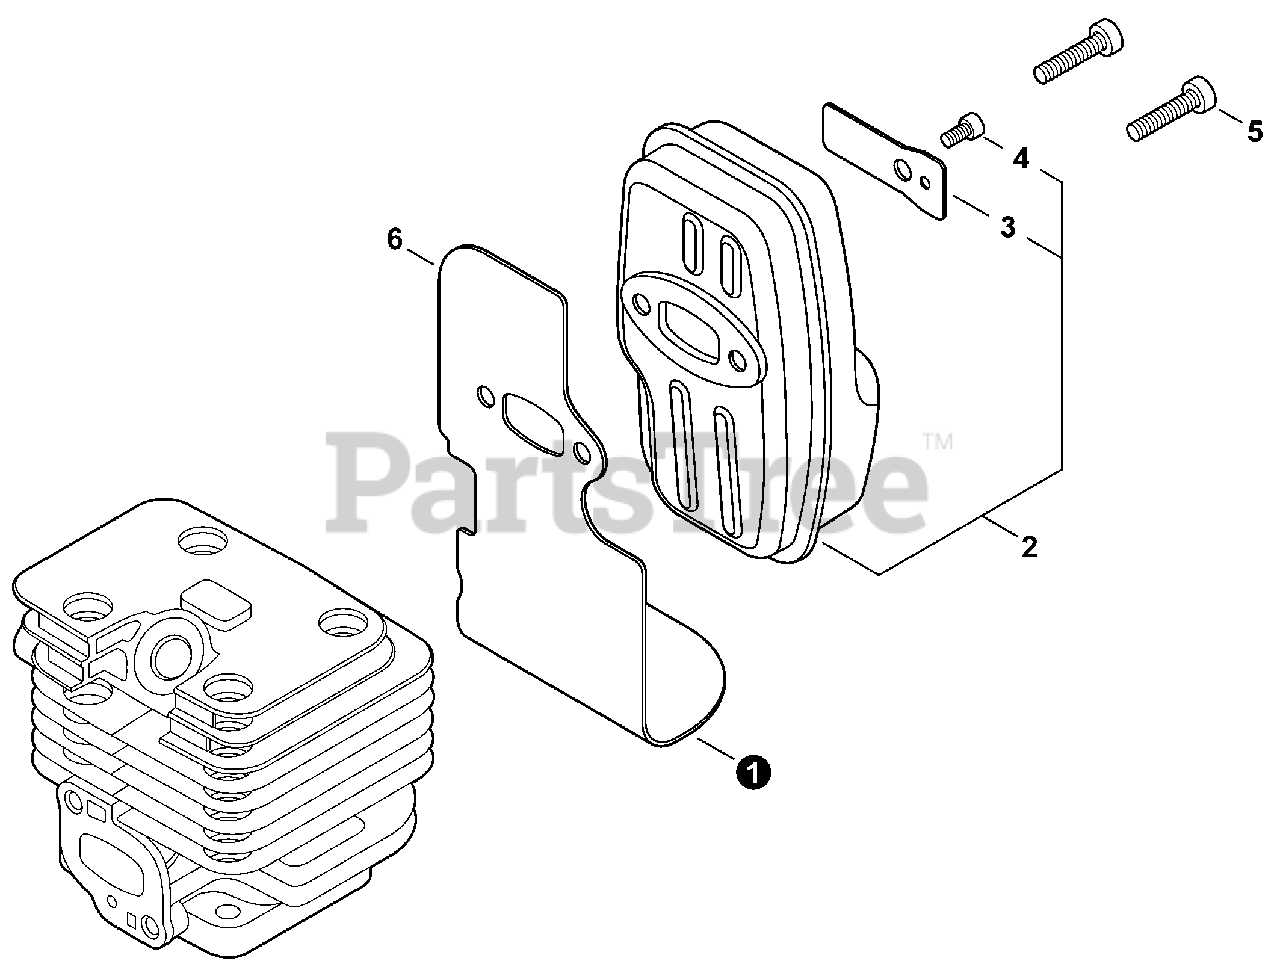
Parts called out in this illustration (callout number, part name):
1	GASKET, EXHAUST
2	MUFFLER ASSY
3	SCREEN, SPARK ARRESTER
4	BOLT, TORX 4×8
5	BOLT, TORX 5×20
6	GASKET KIT
